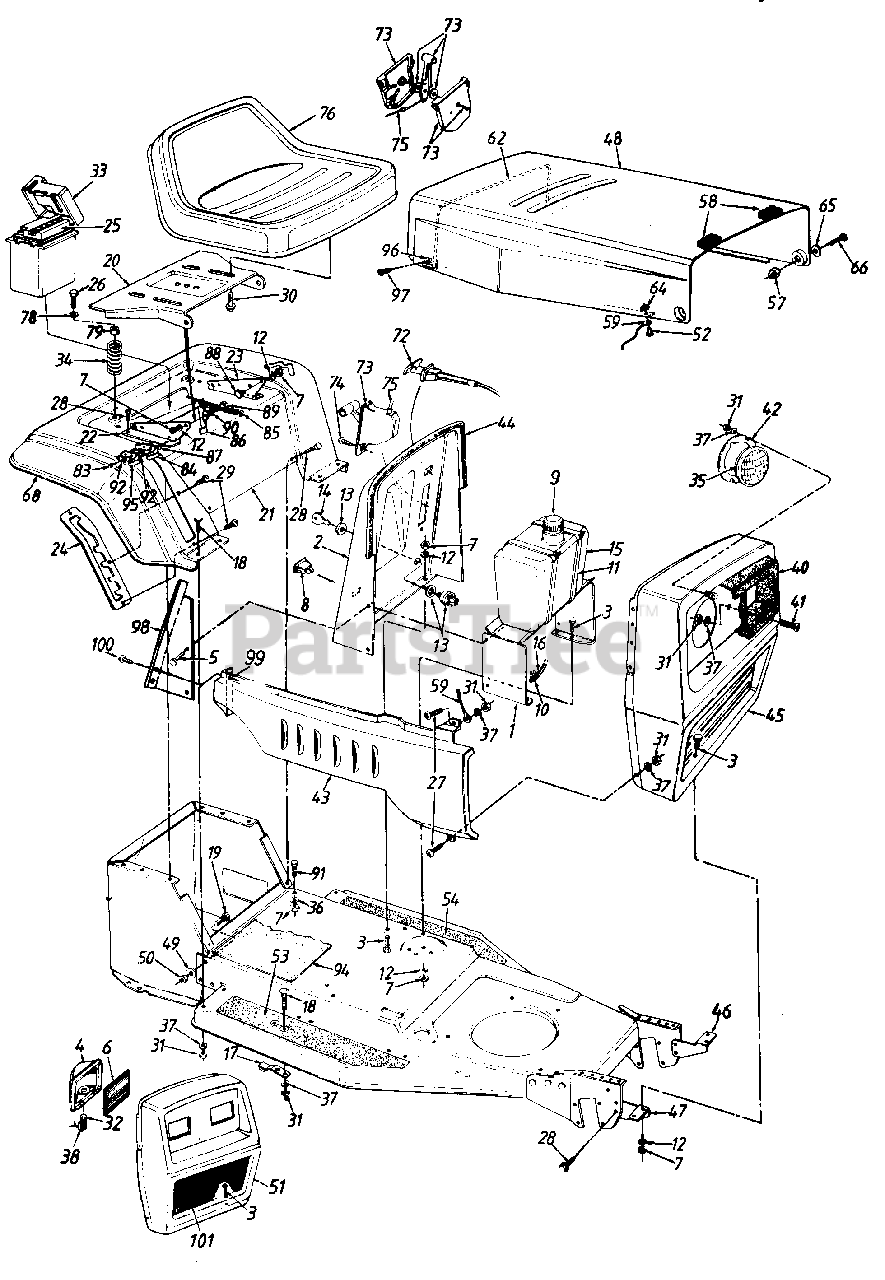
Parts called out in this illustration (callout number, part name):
1	Dash Panel Support Brkt.
4	Headlight Housing
5	Hex AB-Tap Scr. 1/4 x .62"
6	Headlight Lens
7	Hex Nut 5/16-18 Thd.
8	Light Switch
9	Gas Cap
10	Hose Clamp
11	Cable Tie
12	L-Wash. 5/16" I.D.*
13	Ignition Switch
14	Ignition Key
15	Fuel Tank
16	Gas Line-15" Lg.
17	Blade Brake Ass'y.
18	Carriage Bolt 1/4-20 x .62"
19	Ribbed Neck Bolt 3/8-24 x .8"
20	Seat Pivot Brkt.
25	Battery
26	Hex Self-Tap Screw 5/6-18 x 1.25" Lg.
27	Truss Mach. Scr. 1/4-20 x .5" Lg.
28	Hex AB-Tap Scr. 5/16 x .75" Lg.
29	Torx Mach. AB-Tap Scr. 1/4 x .62" Lg.
30	Hex Self-Tap Scr. 3/8-16 x .75" Lg.
31	Hex Nut 1/4-20 Thd.
32	Bulb
33	Battery Box w/Cover
34	Compression Spring
35	Headlightt
36	Bell-Wash. 5/16" I.D.
37	L-Wash. 1/4" I.D.
38	Socket
40	Bezel
41	C-Sunk Mach. Scr. 1/4-20 x 1.5"
42	Headlight Retainer
43	Side Panel-R.H.
44	Trim Strip 31" Lg.
47	Grille Mtg. Brkt.-R.H.
50	Hex L-Nut 3/8-24 Thd.
53	Foot Pad-R.H.
54	Foot Pad-L.H.
57	Lock Nut 1/4-28 Thd.
58	Foam Strip
59	Hood Stop
62	Hood Spring
64	Hex Sems Nut #10-24 Thd.
65	Spr. Wash. .39" I.D. x .62" O.D.
66	Shld. Bolt
68	Trim Strip 81" Lg.
72	Choke Control
73	Throttle Control Box
74	Truss AB-Tap Scr. #10 x .5"
75	Throttle Wire
76	Seat Assembly
78	Flat Wash. .344" I.D. x .88" O.D.
79	Bushing
83	Hex Tap Scr. #8 x .5" Lg.
84	Safety Switch
85	Ext. Spring 5.31" Lg.
86	Seat Lift Brkt.
87	Insulator Boss Plate
88	Shld. Bolt .437" Dia. x .162" Lg.
89	Shld. Bolt .437" Dia. x .268" Lg.
90	Spr. Wash. .445" I.D. x .75" O.D.
91	Hex Wash. Hd. Scr. 5/16-18 x .62" Lg.
92	Insulator Plate
94	Center Foot Pad
95	Safety Switch
96	Hood Spring Retainer
97	Oval Hd. Self-Tap Scr. .5" Lg.
98	Side Panel Mtg. Brkt.-R.H.
99	Speed Nut #10-24 Thd.
100	Truss Mach. B-Tap Scr. #10 x .5" Lg.
101	Grille Screen
